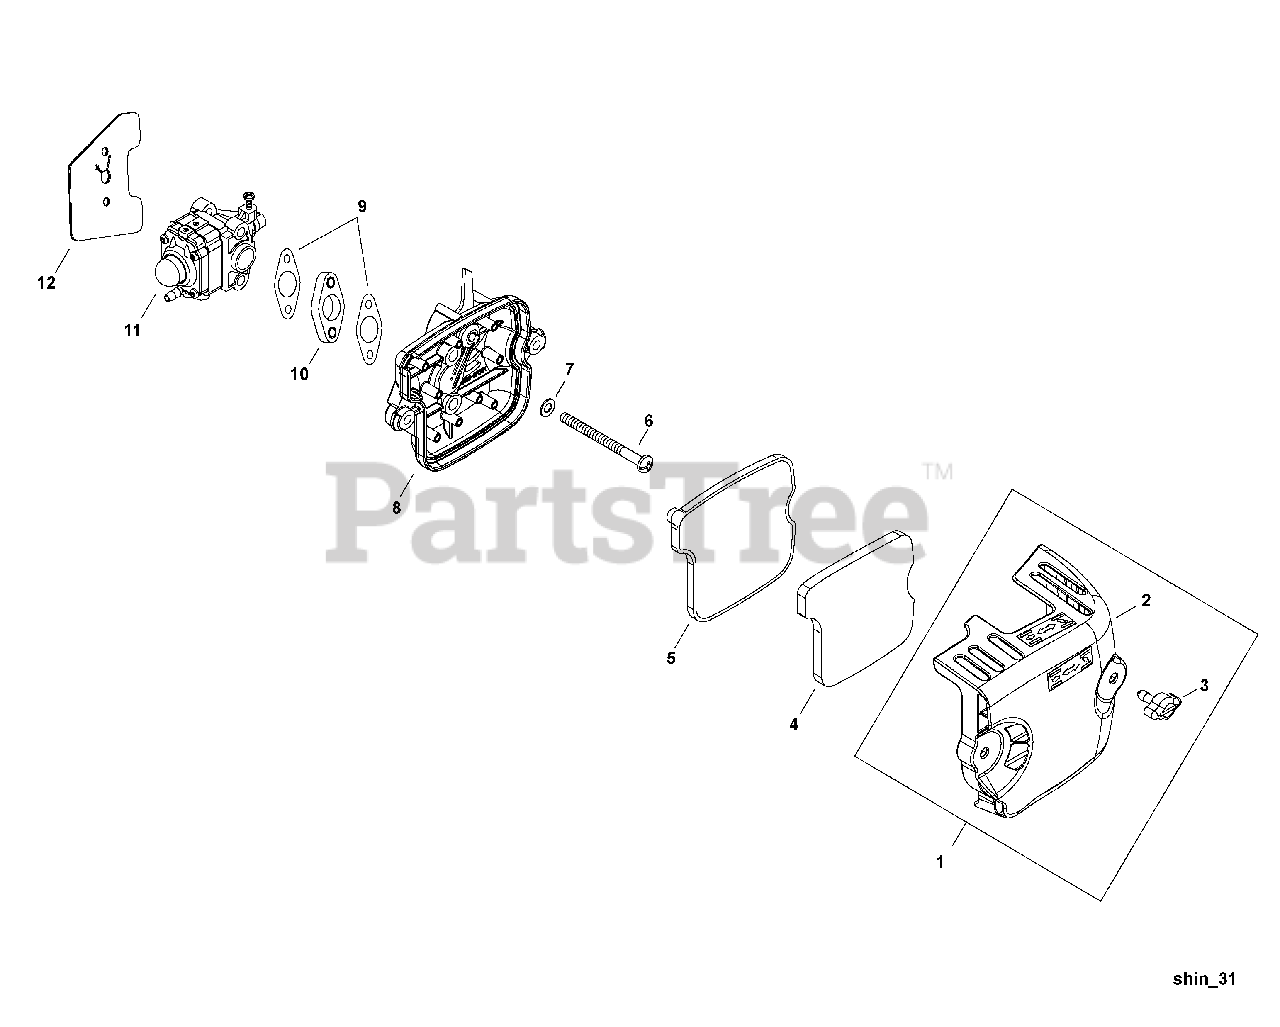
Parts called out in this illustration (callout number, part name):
1	COVER ASSY, AIR FILTER
2	COVER, AIR FILTER
3	THUMBSCREW M5
4	PRE-FILTER, FOAM
5	FILTER, AIR
6	SCREW M5×70
7	WASHER 5.5×12×0.8
8	CASE, AIR FILTER
9	GASKET, INTAKE
12	GASKET, CARBURETOR
